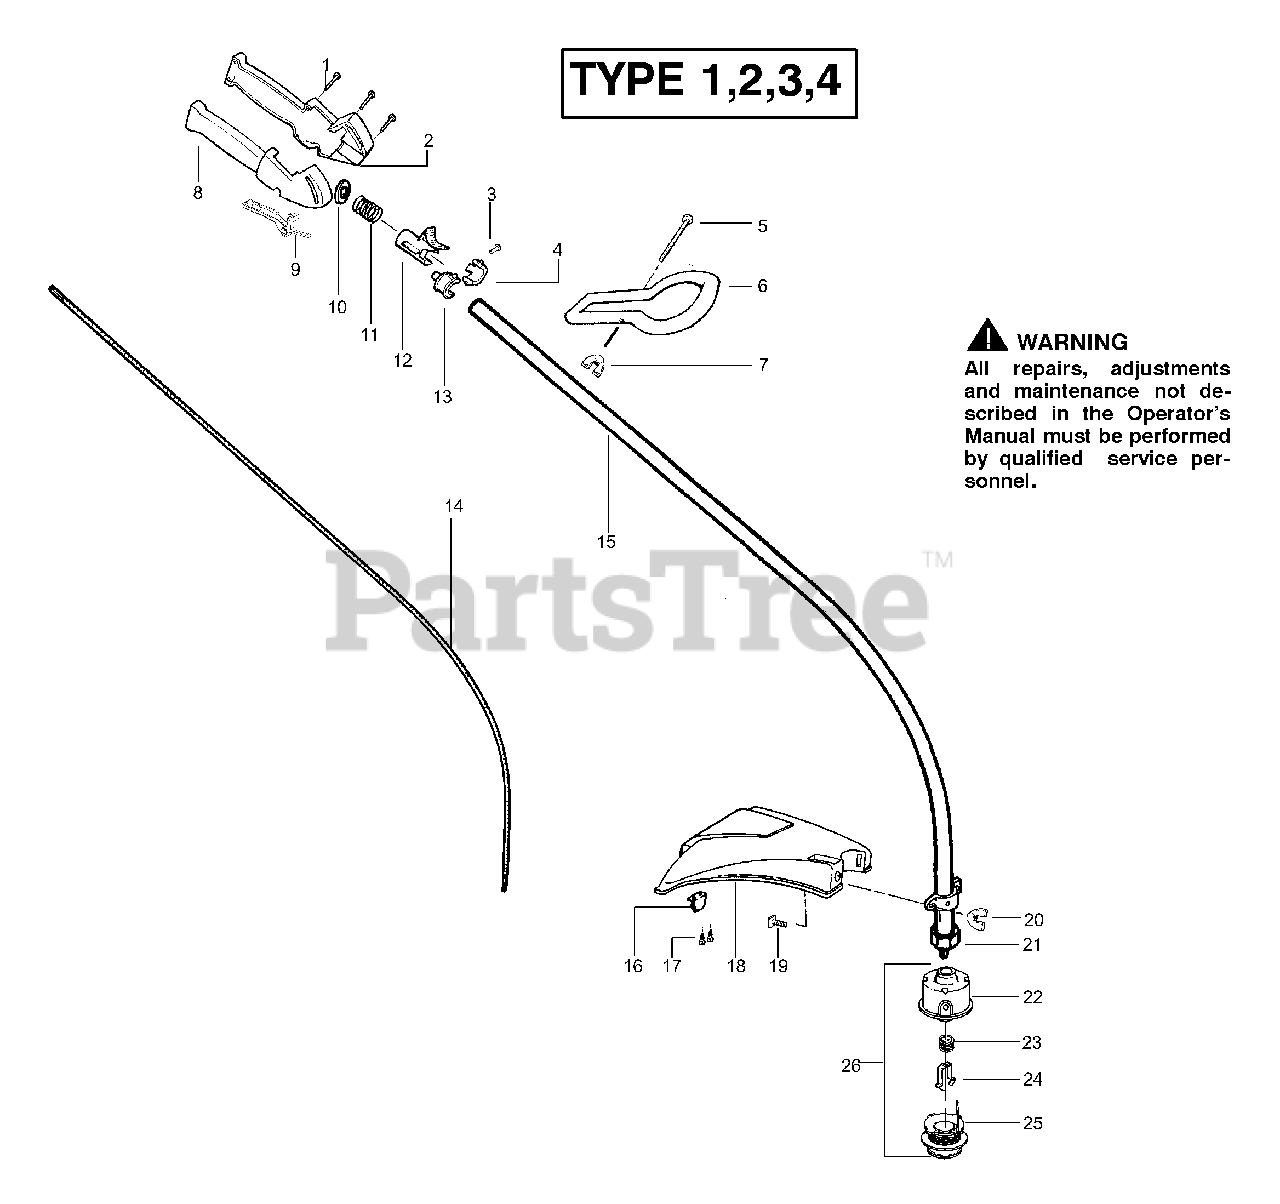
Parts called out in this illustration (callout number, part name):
2	Throttle Hsg. (Left)
3	Screw
4	Locator-left
5	Bolt-Handle
6	Assist Handle
7	Wingnut
8	Throttle Hsg. (Right)
9	Trigger-Throttle
11	Spring-Compression
12	Actuator
13	Locator-right
14	Drive Shaft-Flex
15	Drive Shaft Hsg. Ass'y
16	Line Limiter
17	Screw-Line Limiter
18	Shield Kit Ass'y.
19	Bolt-Shield
20	Wingnut
21	Dust Cup
22	Assy-Hub. (TNG 5)-5/16"
23	Spring-Return
24	Retainer-Spool
25	Accy-Wound Spool
26	Accy-Cutting Head
